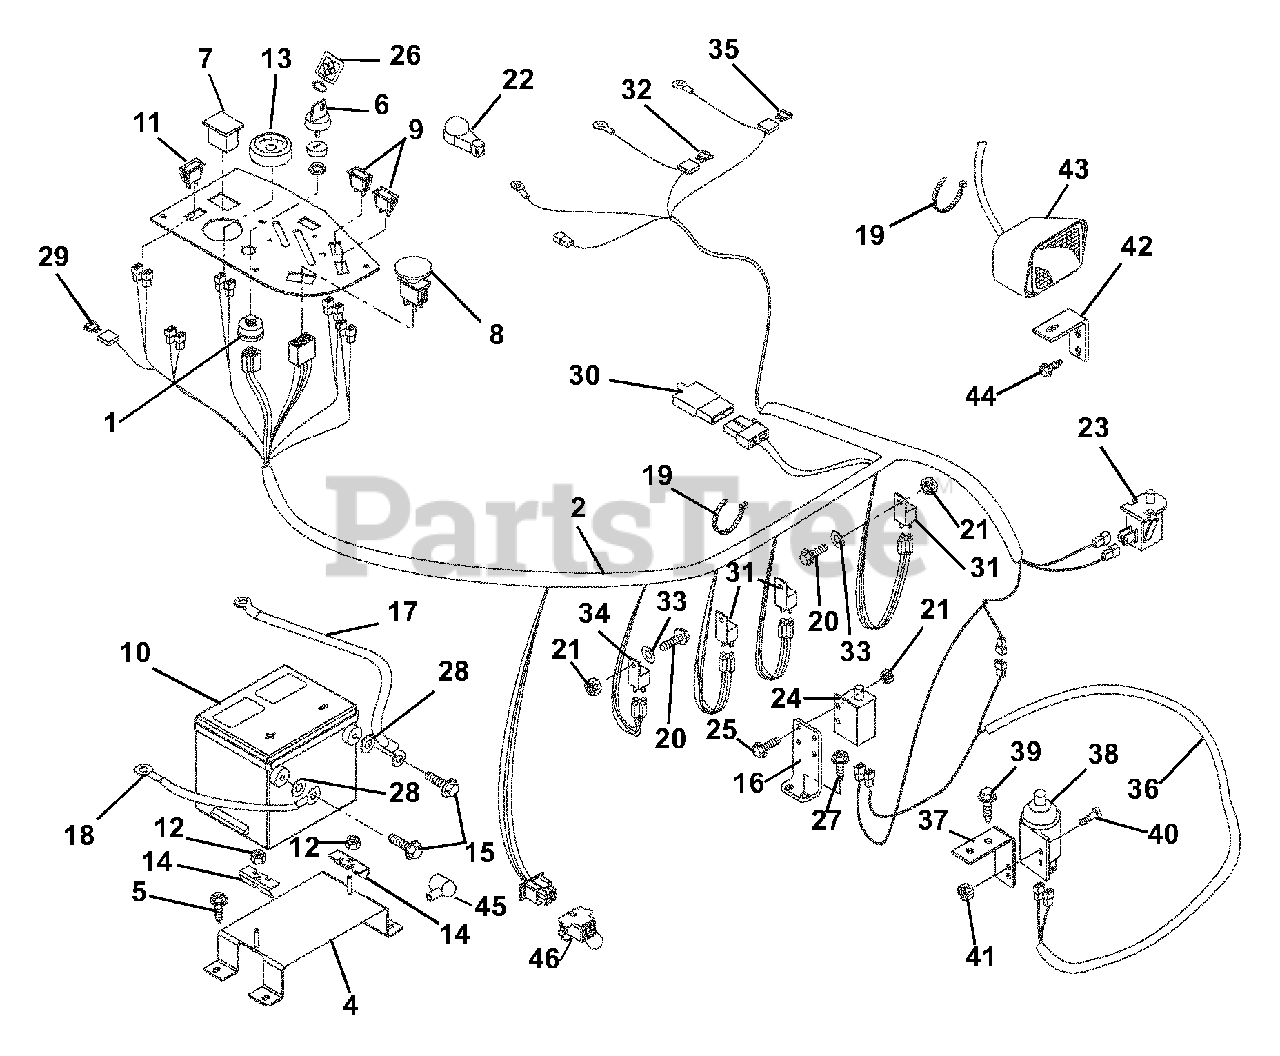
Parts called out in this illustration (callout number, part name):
1	Switch, Ignition (Diesel)
1	Switch, Ignition
2	Harness, Wiring (Diesel)
3	Harness, Wire (Gas)
4	Weldment, Battery Support
5	Screw-Tapping .38-16 x .75 Hex Washer Head
6	Key-with Cap
6	Ignition Key Set
8	Switch-Clutch With Retainer Ring
9	Light-Indicator Kit
10	Battery with Tube
11	Switch, Light
12	Nut-Locking-Top-Flange .31-18
13	Gauge, Temperature
14	Bracket, Battery Hold-Down
15	Bolt-Hex .25-20 x .75 Grade 5
16	Mount, Safety Switch
17	Positive Cable
18	Cable, Negative Battery
18	Ground Cable
19	Cable Tie
20	Screw-Machine 10-24 x .75 Hex Washer Head
21	Nut-Locking-Nylon 10-24 With Insert
22	Eyelet Terminal Boot
23	Switch, Snap Mounting (N.O.)
24	Switch-Single Pole
25	Screw-Machine 10-24 x .75 Hex Washer Head
26	Key Chain
27	Screw-Tapping .25-20 x .50 Hex Washer Head
28	Washer-Flat-Steel .406 x 1.00 x ..083
29	Fuse, 15 Amp
30	Diode, Connector Shell
31	Relay
32	Fuse, 30 Amp
33	Washer-Flat-Steel .25 x .562 x .049
35	Fuse, 50 AMP (Maxi Fuse)
35	Fuse, 25 Amp
36	Harness, Wire Adapter CE
37	Mount- Switch (318, 319)
38	Switch-Single Pole (N.O.) with Cover
39	Screw-Tapping .31-18 x .50 Hex Washer Head
40	Screw-Machine 10-24 x .75 Hex Washer Head
41	Nut-Locking-Nylon 10-24 with Insert
42	Bracket, Headlight Mounting
43	Headlight
44	Screw-Tapping .38-16 x .50 Hex Washer Head
45	Boot, Eyelet Terminal
46	Harness, Eye-Q
